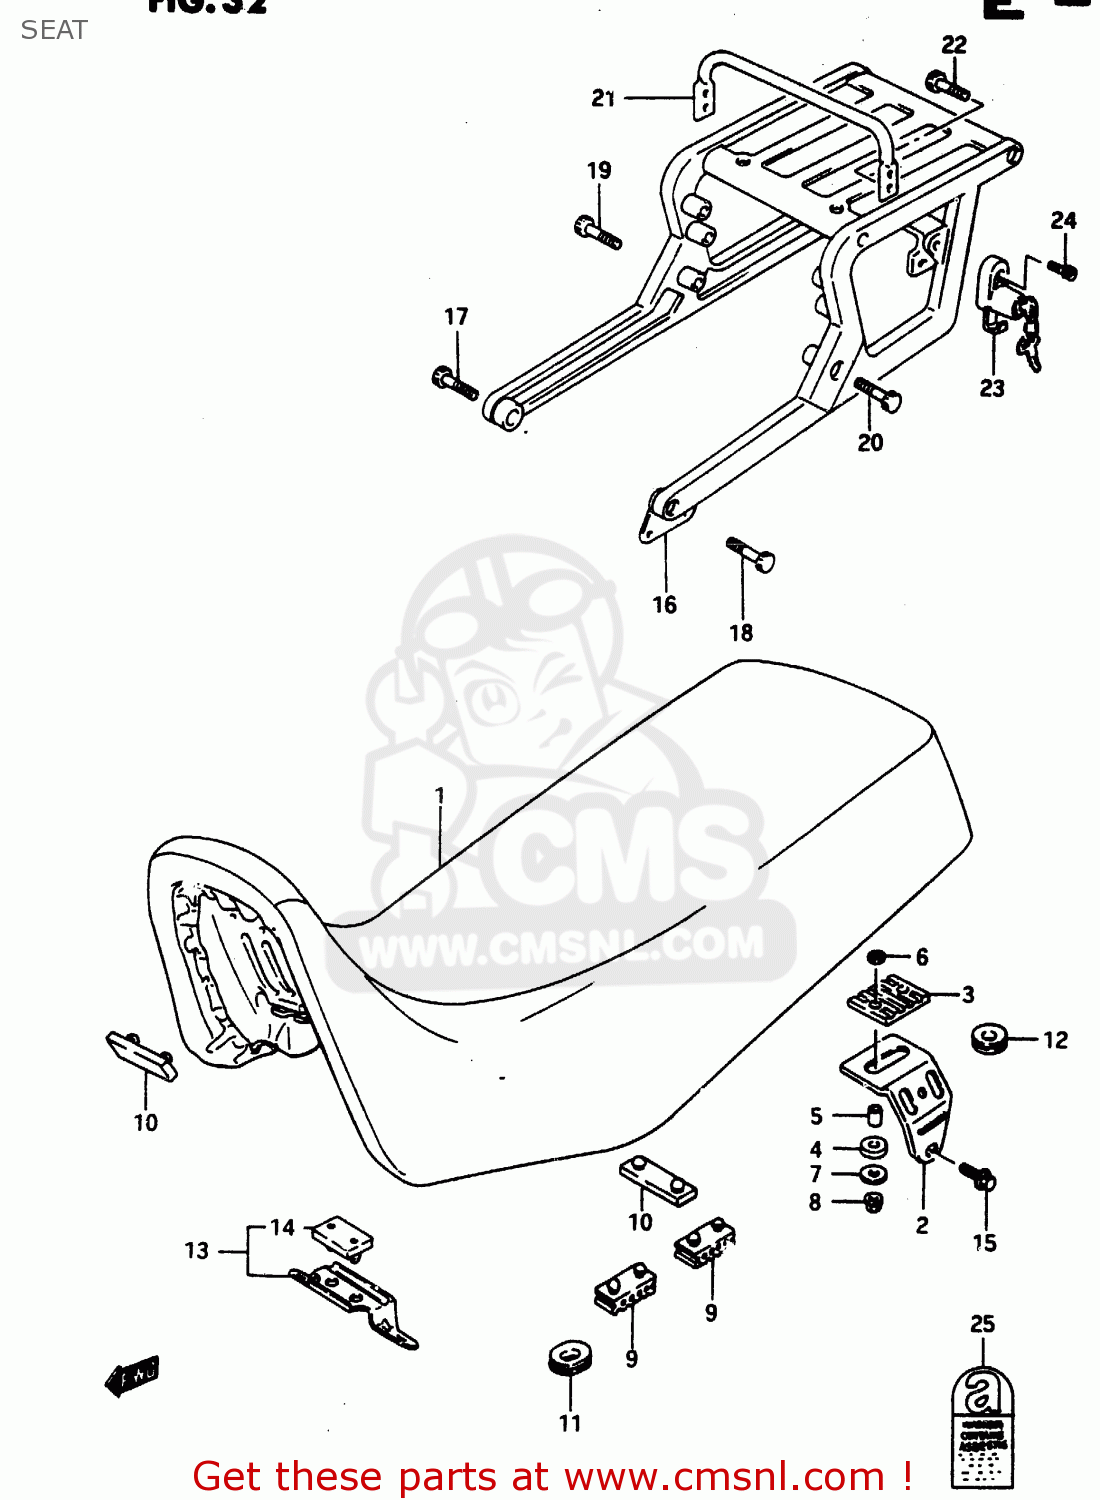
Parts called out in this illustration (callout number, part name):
1	SEAT SET
2	BRACKET,SEAT,LEFT
3	CUSHION,SEAT FR
4	CUSHION,FR PLATE
5	SPACER,SEAT SUPPORT
6	WASHER
7	WASHER, LOWER
8	NUT
9	CUSHION,SEAT(40X20X15)
10	CUSHION
11	CUSHION
12	CUSHION
13	PLATE ASSY,SEAT FR HOOK
14	CUSHION
15	BOLT, 8X1.25X1
16	CARRIER ASSEMBLY,REAR
17	BOLT, FRONT RH
18	BOLT, FRONT LH
19	BOLT, REAR RH
20	BOLT ,8X50
21	TUBE, PILLION HANDLE
22	BOLT 8X16
23	LOCK SET,HELMET
24	BOLT
25	LABEL,ASBESTOS WARNING
